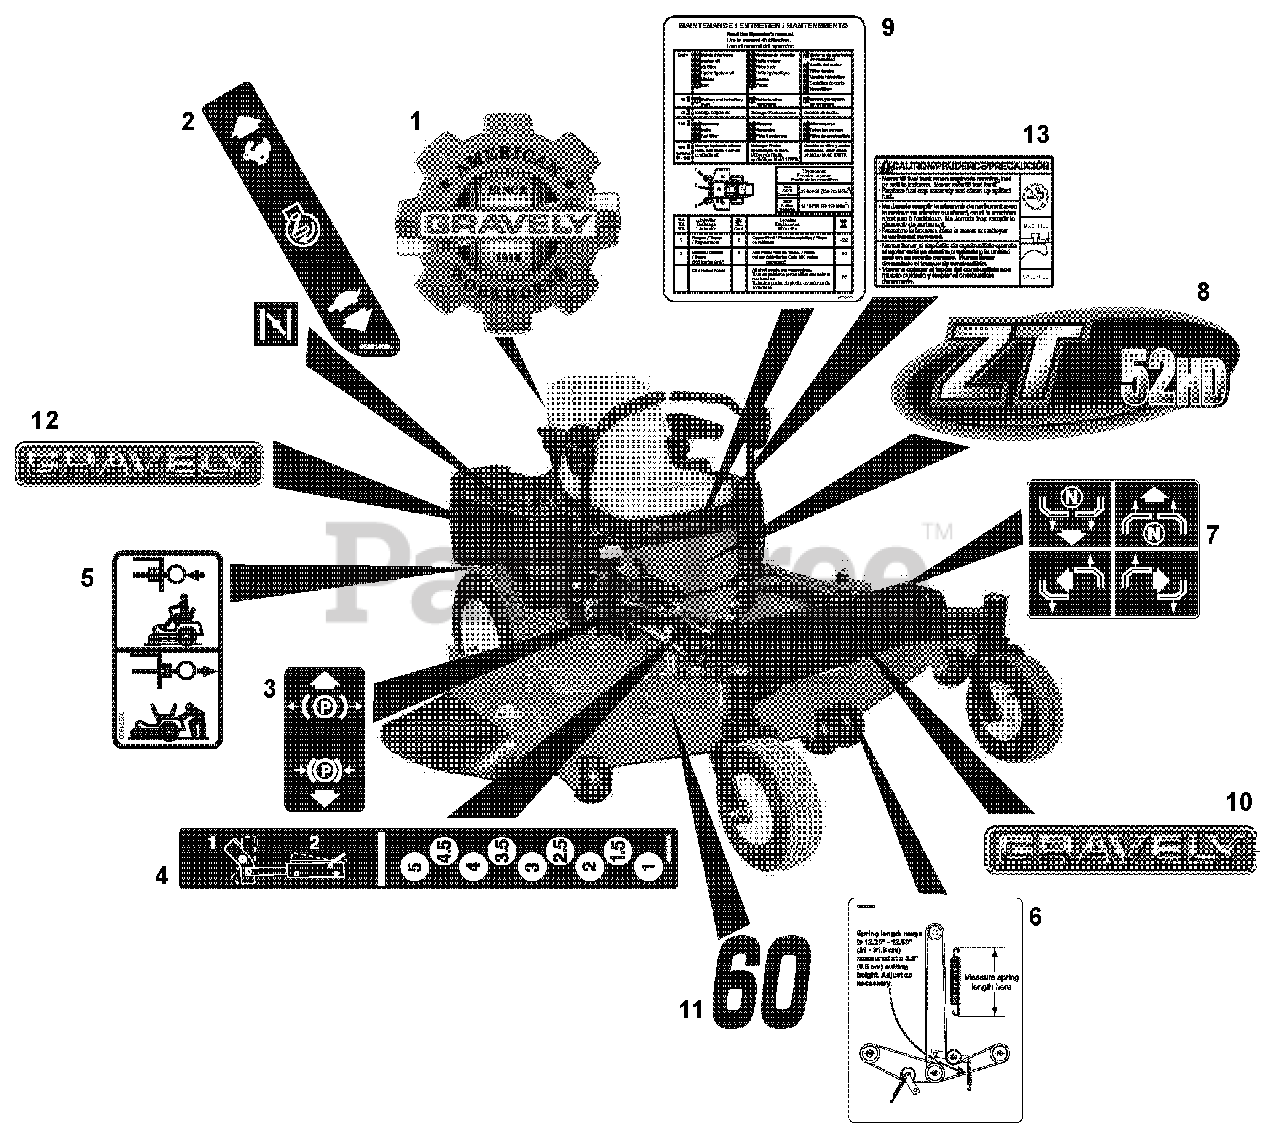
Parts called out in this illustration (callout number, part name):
1	Decal, Gravely Heritage Small
2	Decal, Control
3	Decal, Parking Brake Lever
4	Decal, Height of Cut
5	Decal, Transmission Disconnect
6	Decal, Belt Diagram
7	Decal, Instructional Steering
8	Decal, 44 HD
8	Decal, 48 HD
8	Decal, 52 HD
8	Decal, 60 HD
9	Decal, Maintenance Instructions
10	Decal, 15" Gravely Logo
11	Decal, 60"
11	Decal, 52"
11	Decal, 48"
11	Decal, 44"
12	Decal, Fuel Tank Gravely
13	Decal, Fuel Warning
